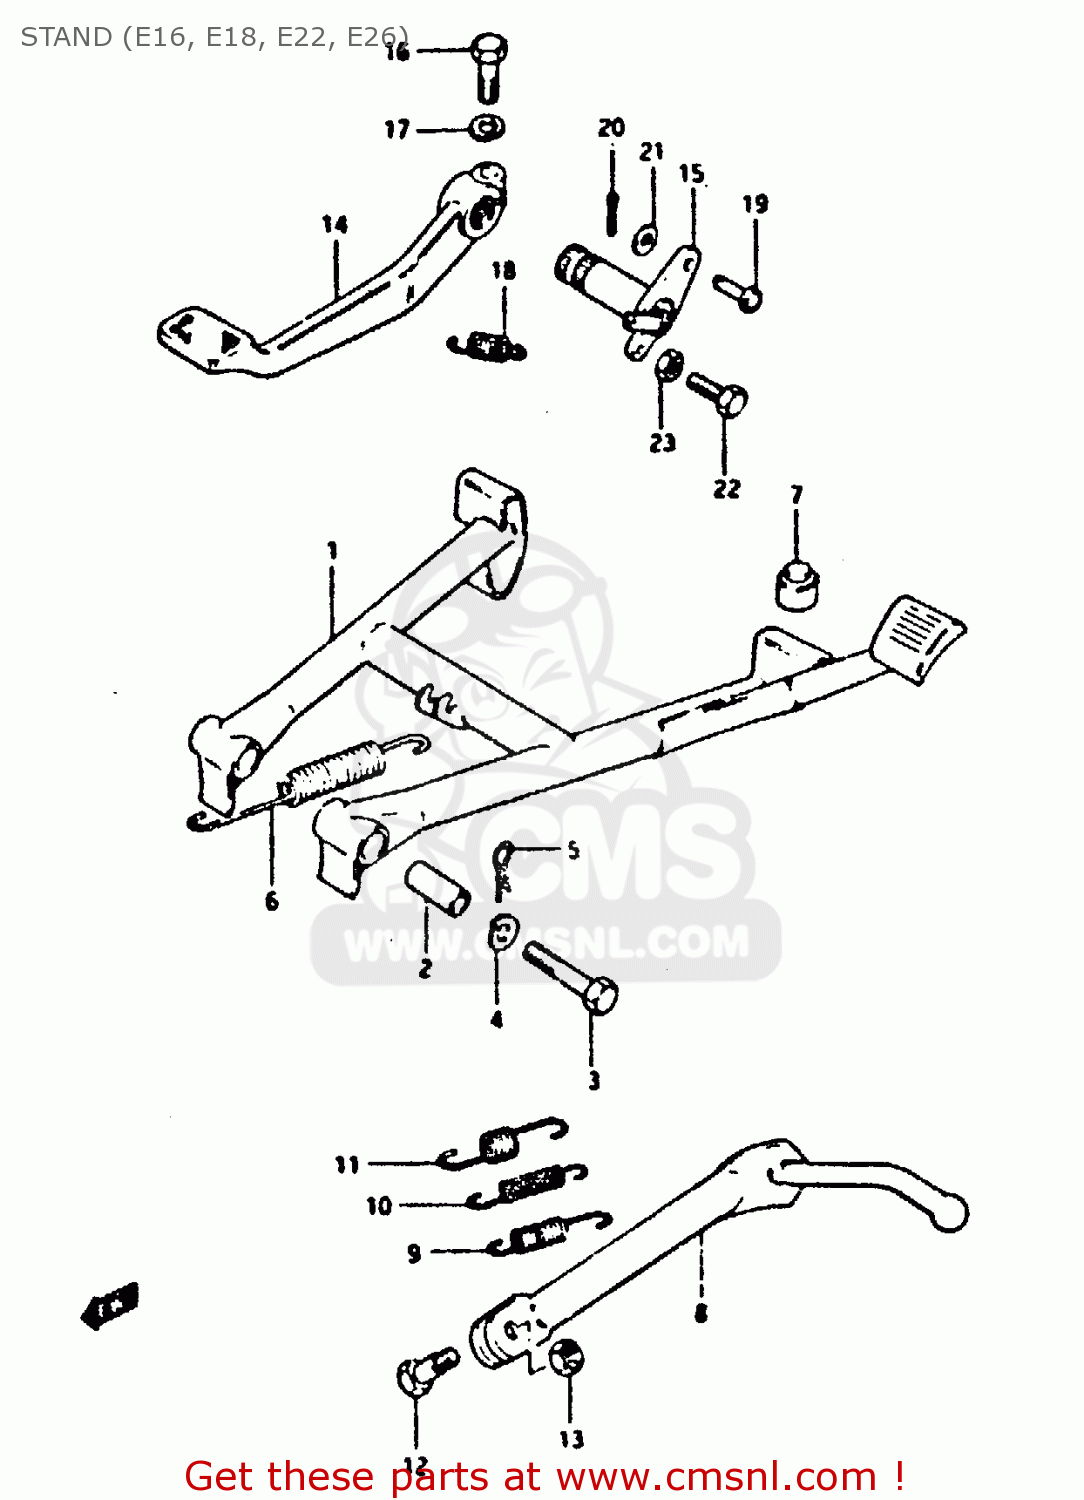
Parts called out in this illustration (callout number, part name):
1	STAND,CENTER
2	SPACER(10X16X38.8)
3	BOLT
4	LOCK WASHER
5	CLIP
6	SPRING
7	CUSHION
8	STAND, PROP
9	SPRING
10	SPRING
11	SPRING, OUTER
12	BOLT L:30
13	NUT
14	PEDAL,BRAKE
15	ARM,BRAKE PEDAL
16	BOLT
17	LOCK WASHER
18	SPRING
19	PIN
20	PIN
21	WASHER
22	BOLT(6X25)
23	NUT
